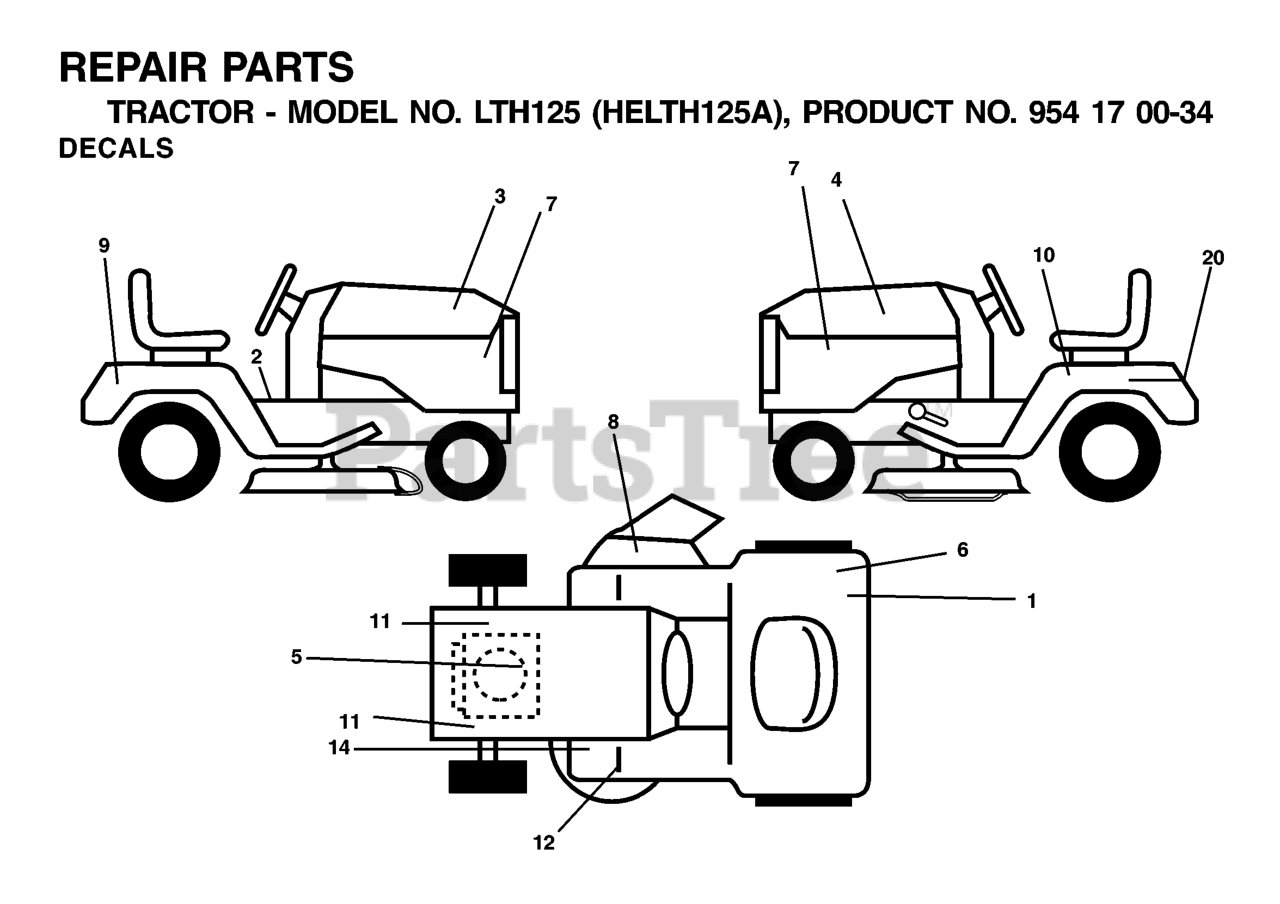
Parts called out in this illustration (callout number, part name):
1	DECAL CERTIFICATION
2	DECAL PARK BRAKE
6	DECAL EUROPE STANDARD CE
7	DECAL PNL SIDE
8	DECAL MOWER CUT/FINGER
9	DECAL FENDER HUSQ
10	DECAL READ OWNER'S MAN SYMS
12	DECAL
14	DECAL V-BELT SCHEMATIC
20	DECAL BTRY SYMBOLS
